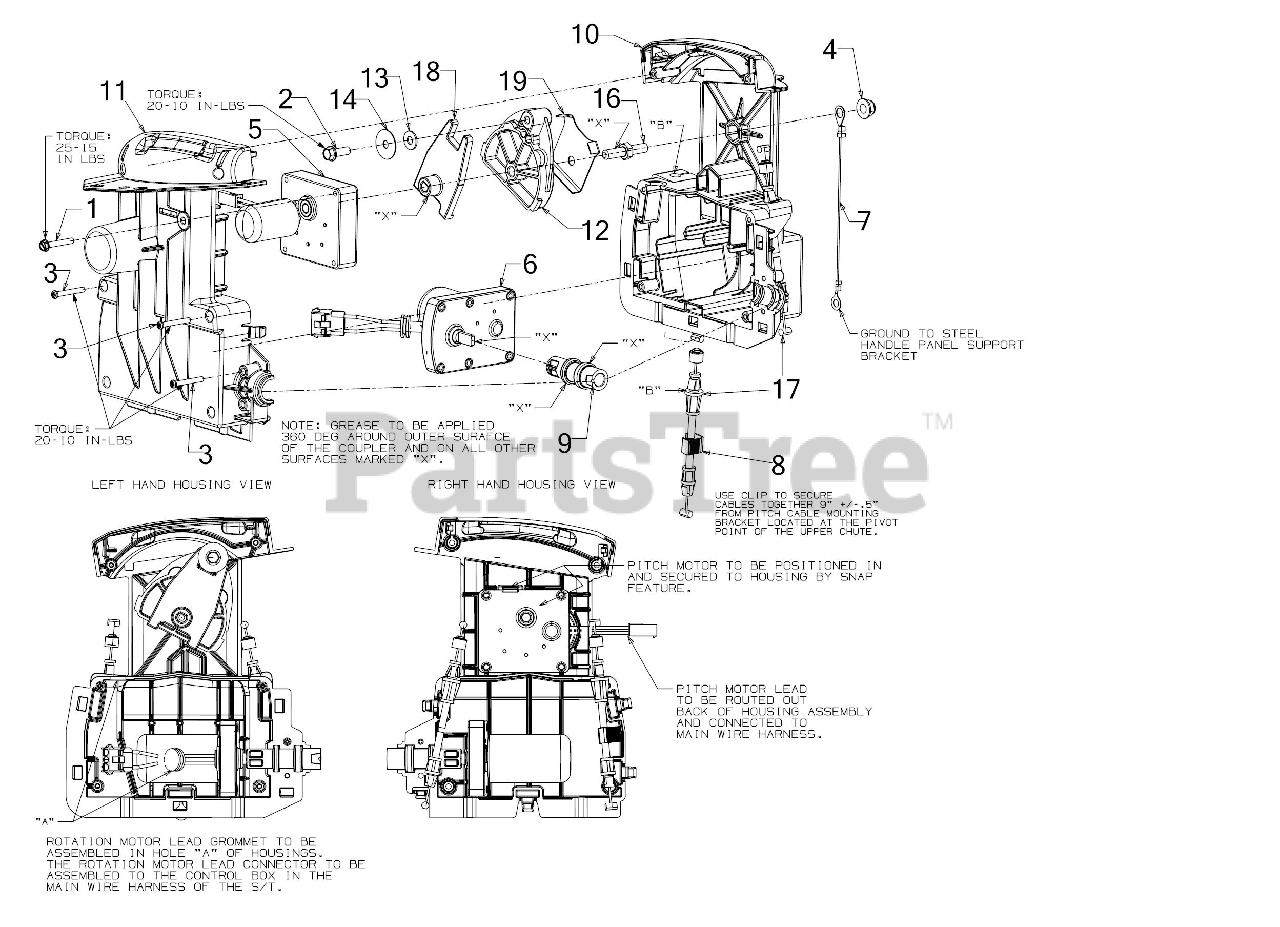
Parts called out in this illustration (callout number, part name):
1	HEX SCREW HEAD #10-16 x 1.25
2	SCREW 1/4-15 x .750
3	SCREW #8-18 x 1.250
4	FLANGE LOCK NUT 5/16-18
5	CHUTE PITCH MOTOR
6	CHUTE ROTATION MOTOR (NO PITCH)
7	CHUTE GROUND WIRE
8	CABLE CLIP
9	ELECTRIC CHUTE COUPLER
10	4 WAY CHUTE HOUSING
11	4 WAY CHUTE HOUSING
12	CABLE GUIDE
13	FLAT WASHER
14	FLAT WASHER
16	SHOULDER SCREW
17	4-WAY CHUTE CABLE
18	CHUTE PITCH ADAPTER
19	CHUTE BRACKET GROUND
